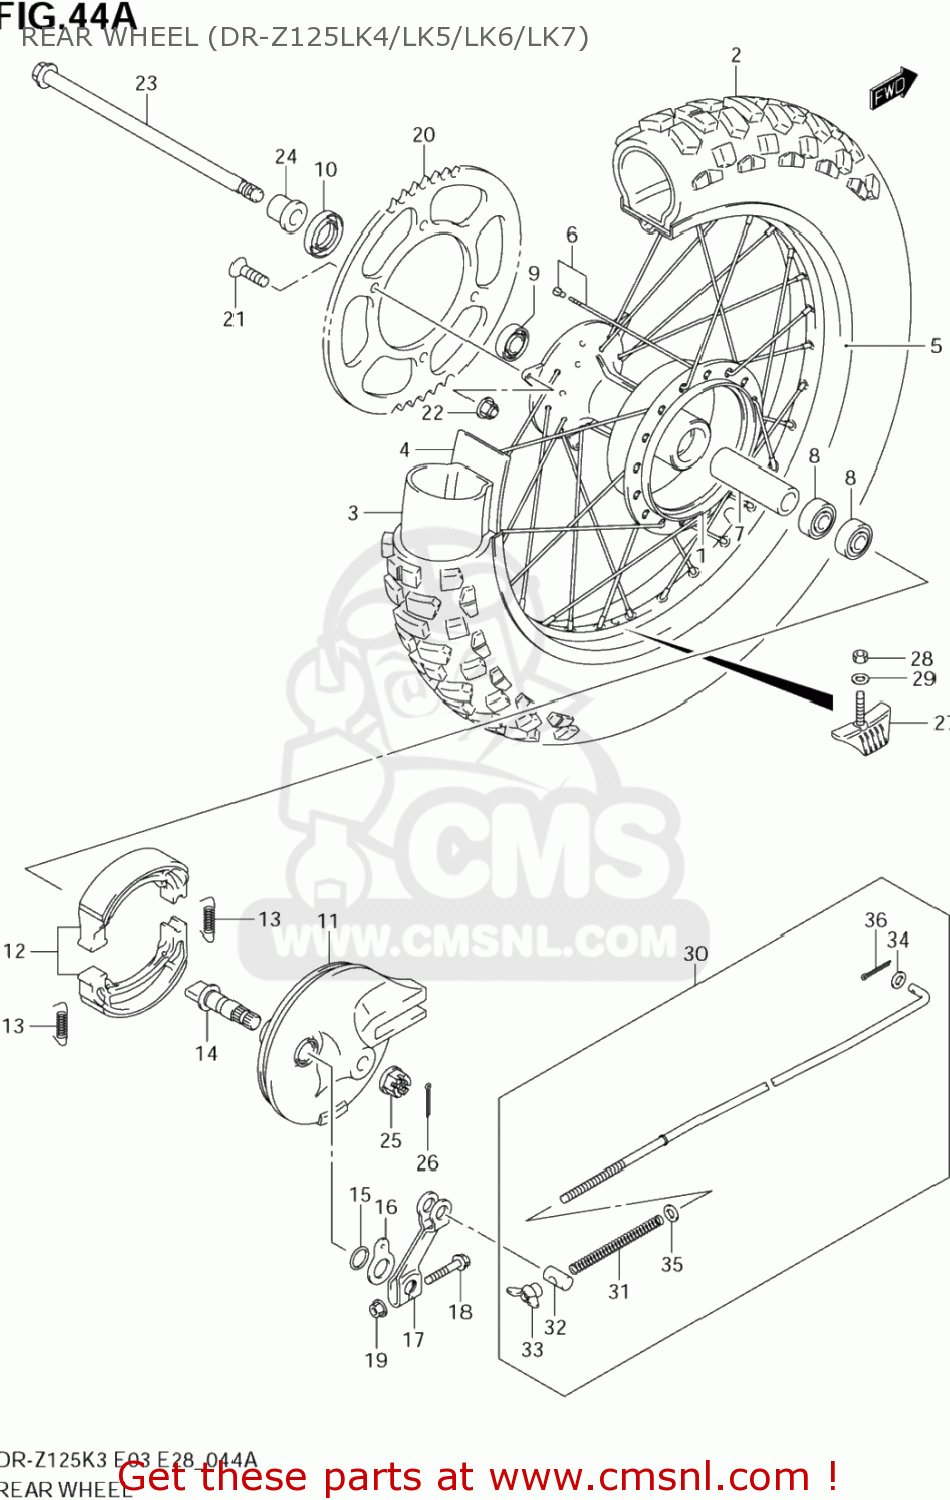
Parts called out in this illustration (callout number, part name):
1	HUB,RR WHEEL
2	TIRE,RR
3	TUBE ASSY,WHEEL INNER
4	PROTECTOR,WHL INR TUBE
5	RIM,RR WHEEL(16X1.60)
6	SPOKE SET,RR WHEEL
7	SPACER(12.5X19X45.5)
8	BEARING
9	BEARING
10	SEAL,OIL(20X37X7)
11	PANEL,RR BRAKE ANCHOR
12	SHOE SET,BRAKE (NAS)
13	SPRING
14	CAM,RR BRAKE
15	O RING(D:2.5,ID:13.8)
16	PLATE,BRAKE LINING INDICATOR
17	LEVER,RR BRAKE CAM
18	BOLT
19	NUT
20	SPROCKET,RR(57T-428)
21	BOLT(8X30.5)
22	NUT
23	AXLE,RR
24	SPACER,RR AXLE
25	NUT
26	PIN, COTTER
27	STOPPER,BEAD
28	NUT
29	WASHER
30	ROD ASSY,RR BRAKE
31	SPRING
32	PIN(11X18)
33	NUT
34	WASHER
35	WASHER
36	PIN 20X20
